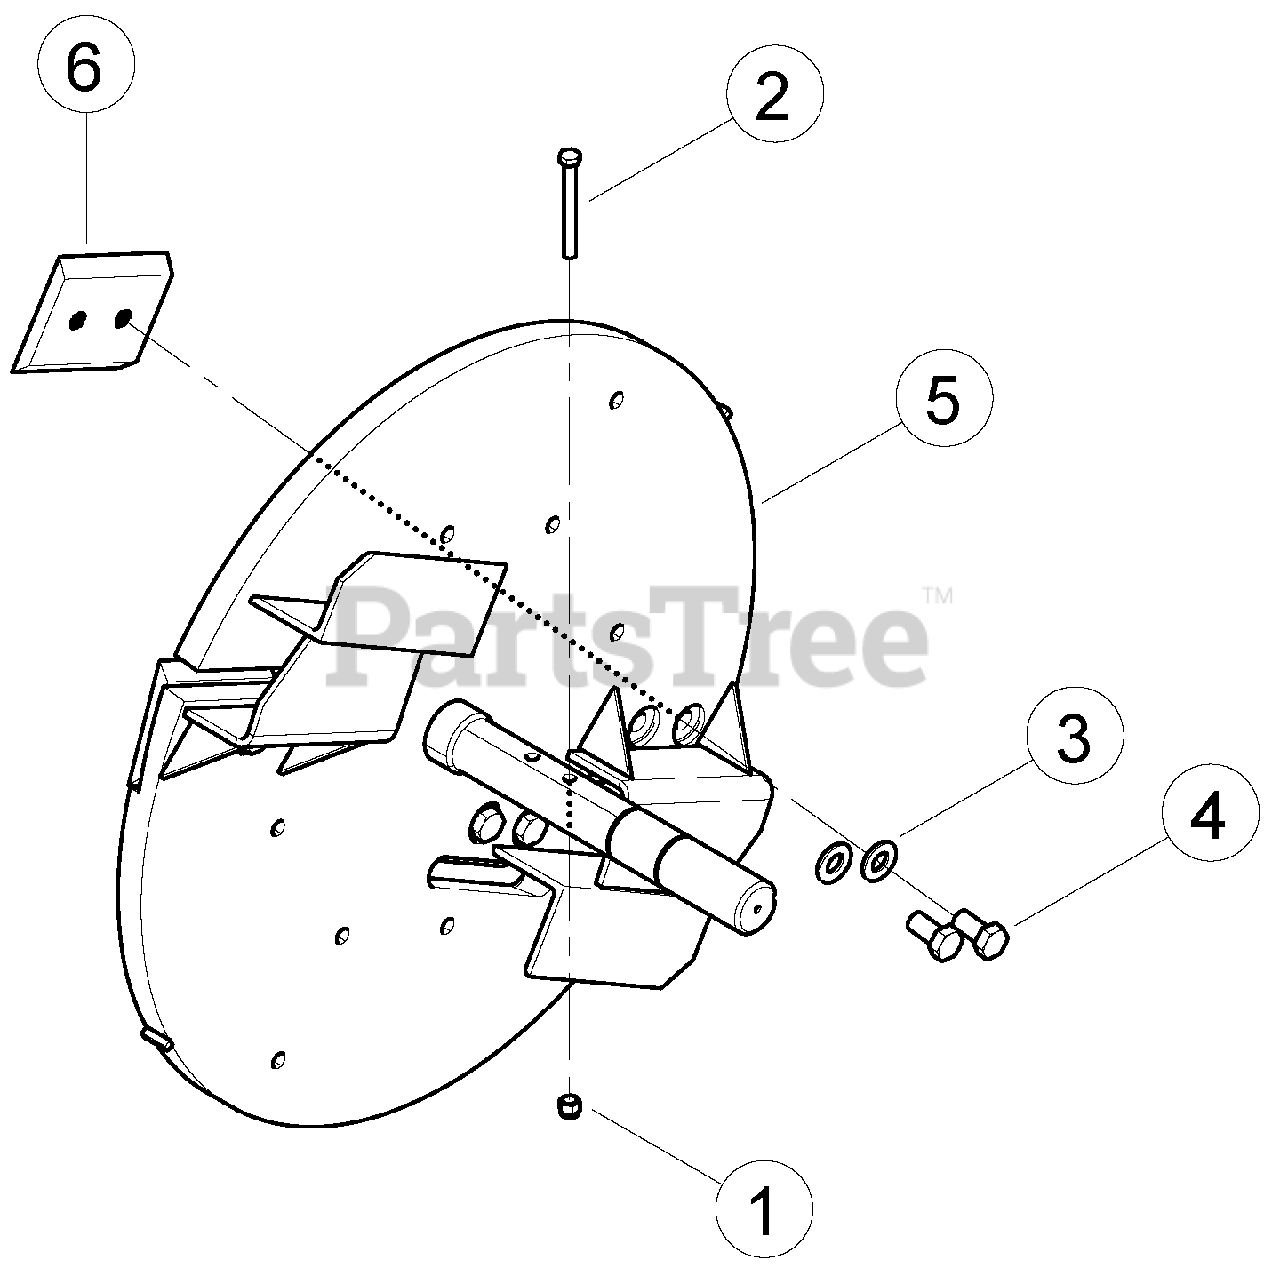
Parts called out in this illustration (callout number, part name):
1	NUT, 3/8 NYLOCK
2	BOLT, 3/8 NC X 3-1/2 FULL THD GR5 ZP
3	WASHER, 5/8 SAE HRD
4	BOLT, M16 X 2.0 X 30 HEX HD W/PATCH
5	WELDMENT, 6 IN. CHIPPER DISK
